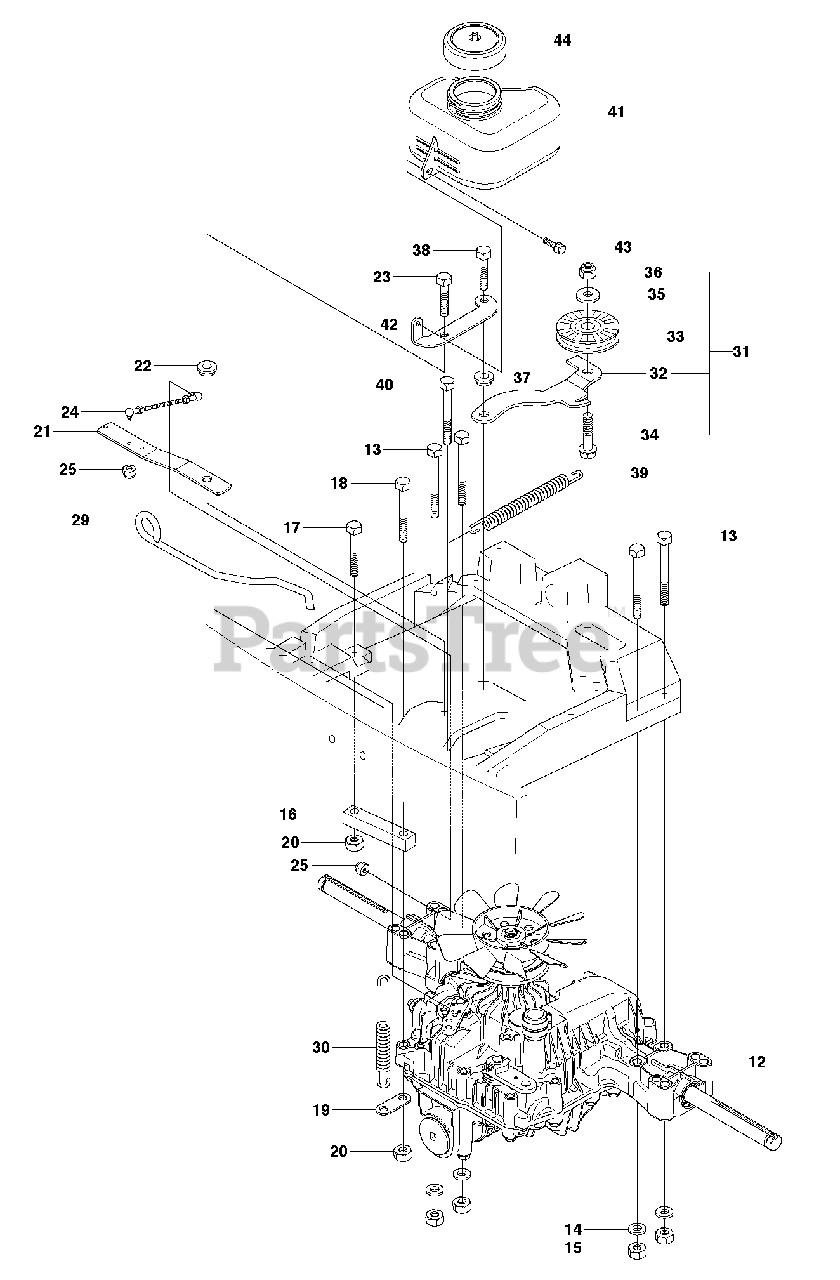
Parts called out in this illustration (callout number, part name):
12	HYDRAULMOTOR
14	WASHER BRB 8.4X17
15	NUT
19	CONNECTOR
20	NUT
22	WASHER
23	SCREW 8X20
25	LOCKNUT M5
30	SPRING
31	TENSIONER
32	TENSIONER
33	PULLEY
34	SCREW
35	SPACER
36	LOCKNUT M8
37	WASHER
38	SCREW 8X20
